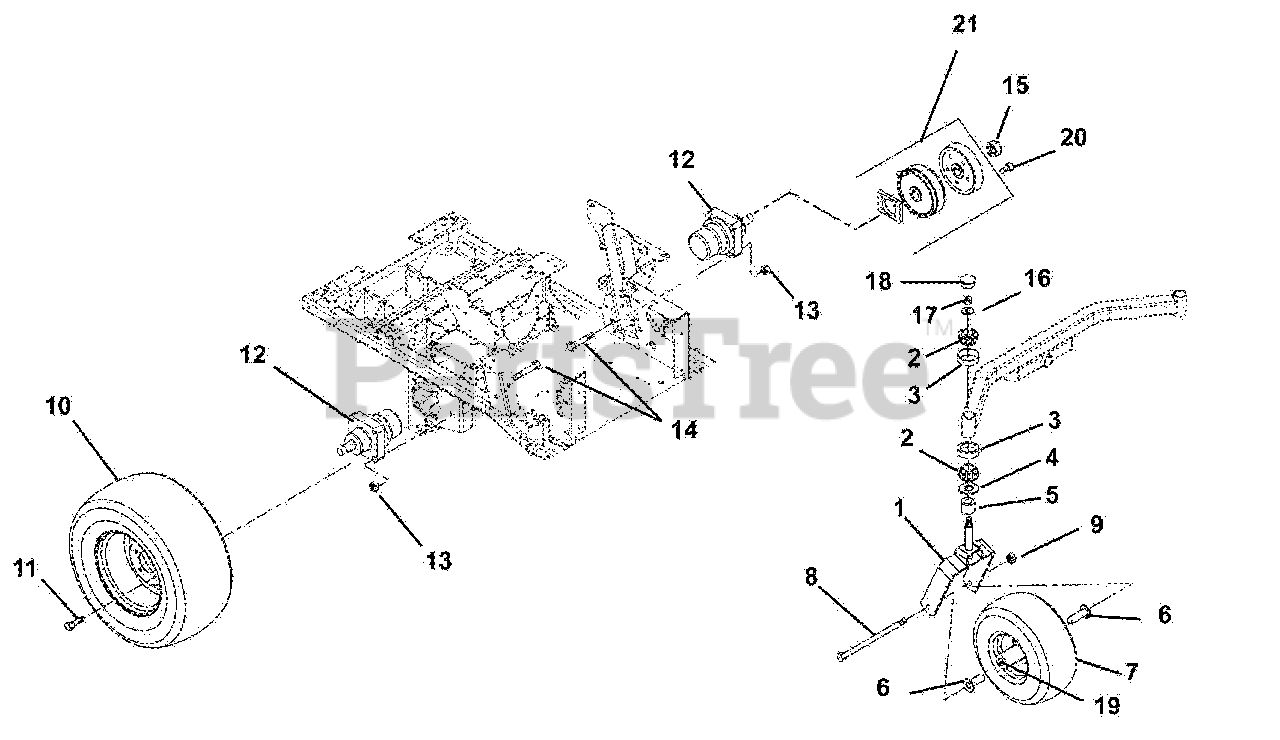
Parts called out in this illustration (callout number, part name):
1	Fork, Front
2	Bearing, Cone w/ Grease
3	Bearing, Cup 1.980 x .420
4	Bearing Seal 1.5 x 2 x .18
5	Spacer, PM, 1.03 I.D. x 1.5 O.D. x .375
6	Spacer, Wheel
7	Wheel/Tire Assembly 15 x 6-6
8	Bolt, Hex .50-13 x 9.00 Grade 5
9	Nut, Locking Center .50-13
10	Tire/Wheel Assembly 24 x 12-12
11	Bolt, Lug .50-20 x 1.38 Grade 8, 60 Degree
12	Hydraulic Wheel Motor (Includes item 15)
13	Nut, Locking Top Flange .50-13
14	Bolt, Wheel Motor .50-13 x 2.75
15	Nut, Lock Jam Patch (Included with 12)
16	Washer, Flat Steel 812 x 1.50 x .135
17	Nut, Jam Center-Lock .75-16
18	Cap, Dust
19	Bearing, 25mm I.D. x 52mm OD x 15mm
20	Bolt, Hex .31-18 x 1.5 Grade 5
21	Kit, Parking Brake Service
